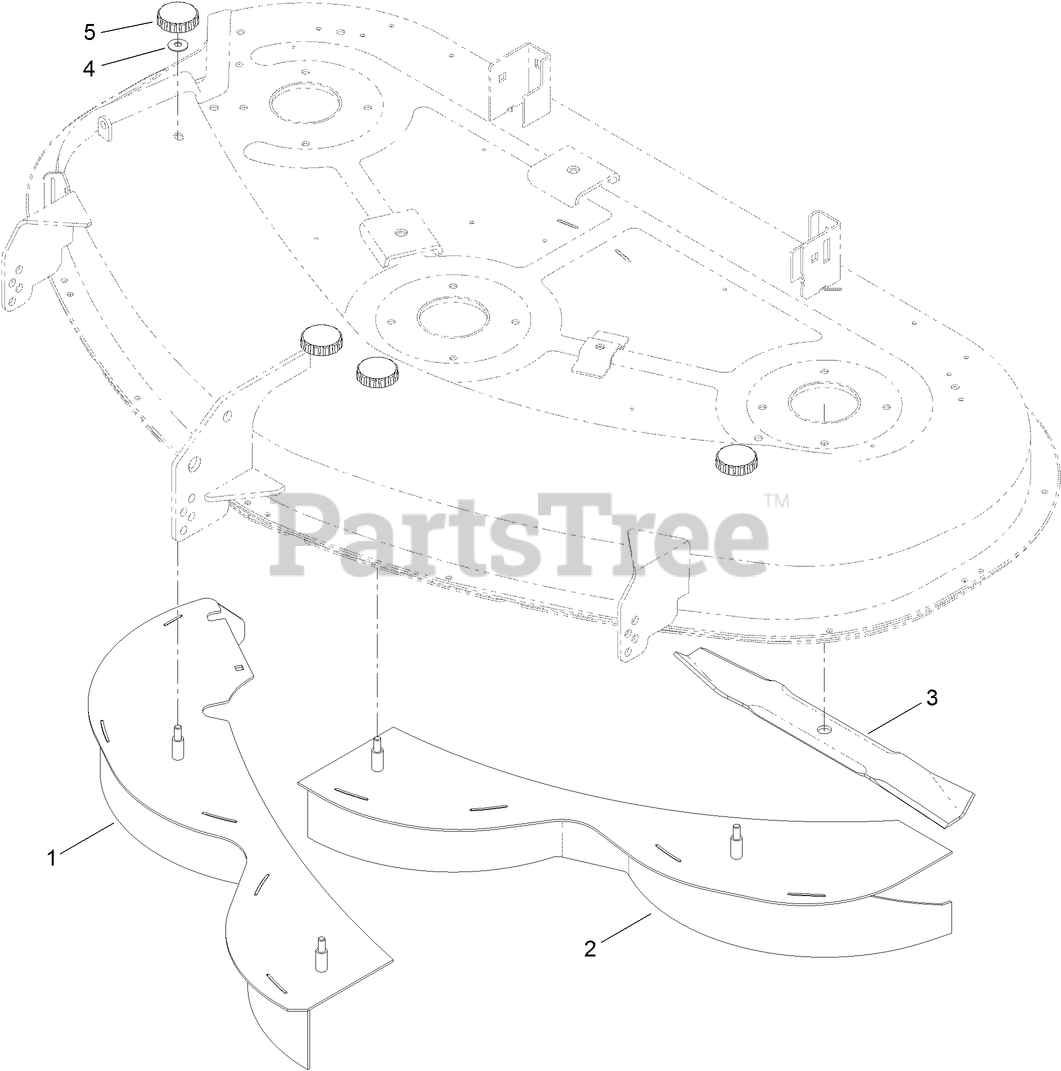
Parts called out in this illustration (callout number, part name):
1	RH BAFFLE ASM
2	LH BAFFLE ASM
3	BLADE-MULCH, 17.50 INCH
4	WASHER-BELLEVILLE
